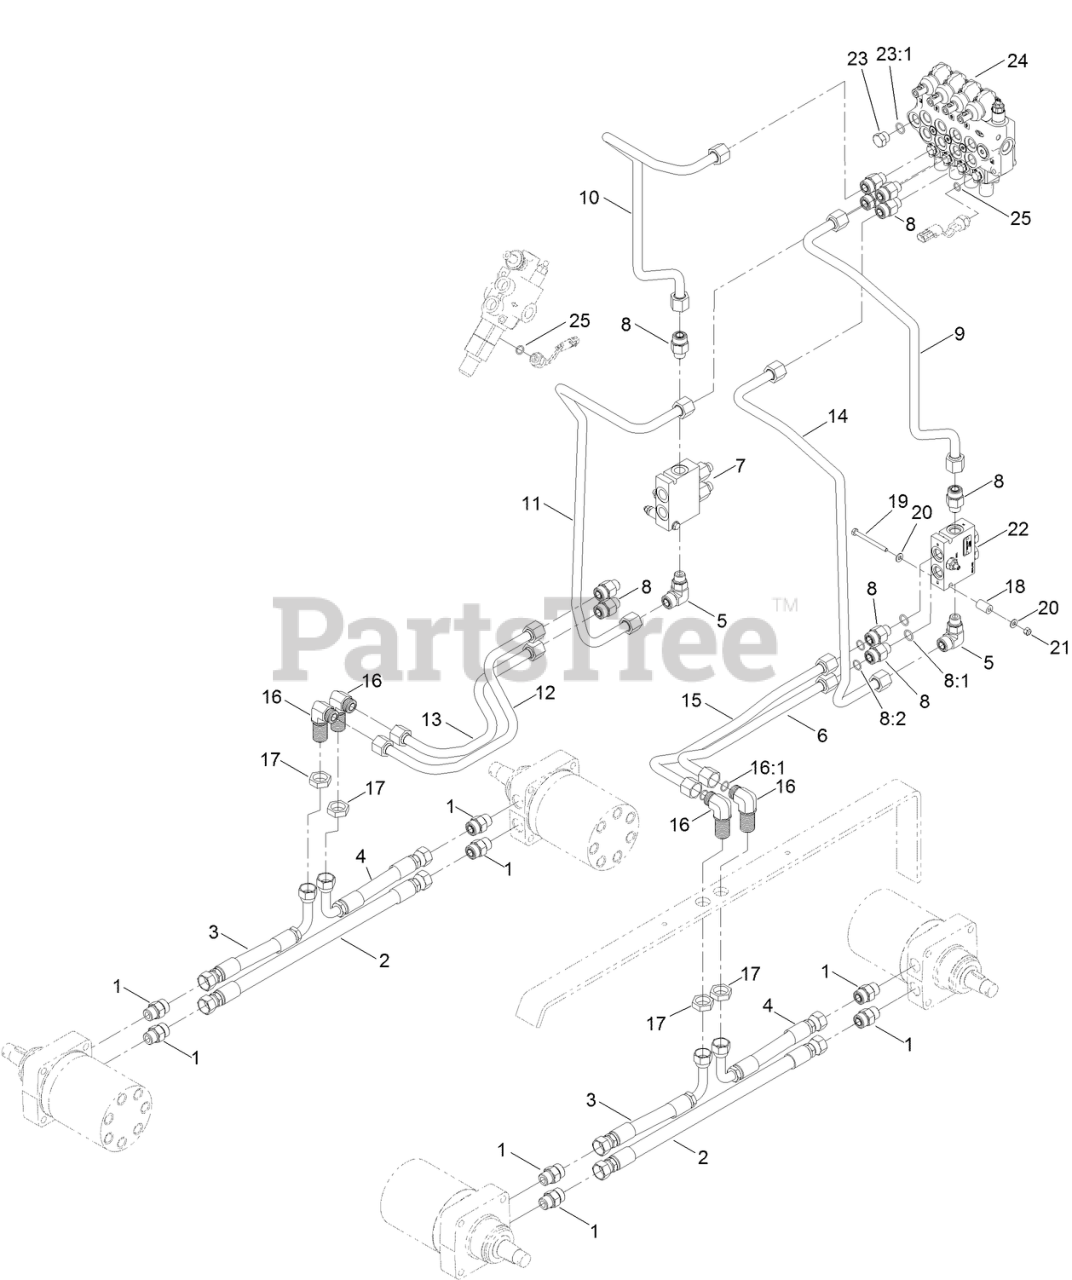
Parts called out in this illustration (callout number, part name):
1	FITTING-STRAIGHT
2	HOSE-HYD
3	HOSE-HYD
4	HOSE-HYD
5	FITTING-ELBOW, 90 DEG
6	TUBE-HYD
7	HYD COUNTERBALANCE VALVE ASM
8	FITTING-STRAIGHT
8:1	O-RING
8:2	O-RING
9	TUBE-HYD
10	TUBE-HYD
11	TUBE-HYD
12	TUBE-HYD
13	TUBE-HYD
14	TUBE-HYD
15	TUBE-HYD
16	FITTING-BULKHEAD, 90 DEG
16:1	O-RING
17	NUT-LOCK, BULKHEAD
18	SPACER-VALVE
19	SCREW-HH
20	WASHER-FLAT
21	NUT-LOCK, NI
22	MANIFOLD-HYDRAULIC
23	PLUG-HYD, HH
23:1	O-RING
24	VALVE-HYDRAULIC, 4-SPOOL
25	O-RING
